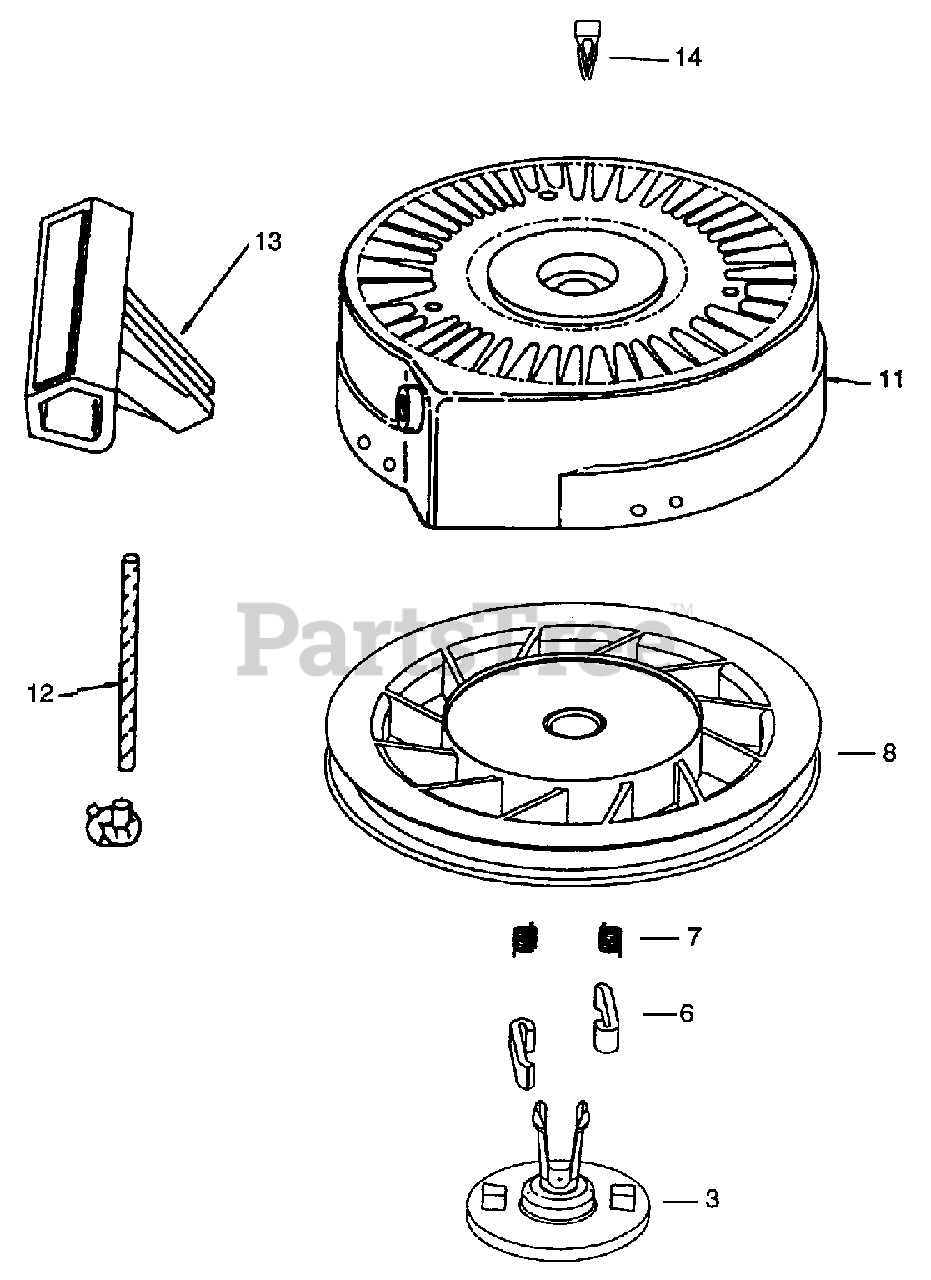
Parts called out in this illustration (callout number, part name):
3	Retainer
6	Starter Dog
7	Dog Spring
8	Pulley & Rewind Spring Ass'y
11	Starter Housing Ass'y
12	Starter Rope (Length 98" x 9/64" Dia.)
13	Starter Handle
14	Locking Tab
